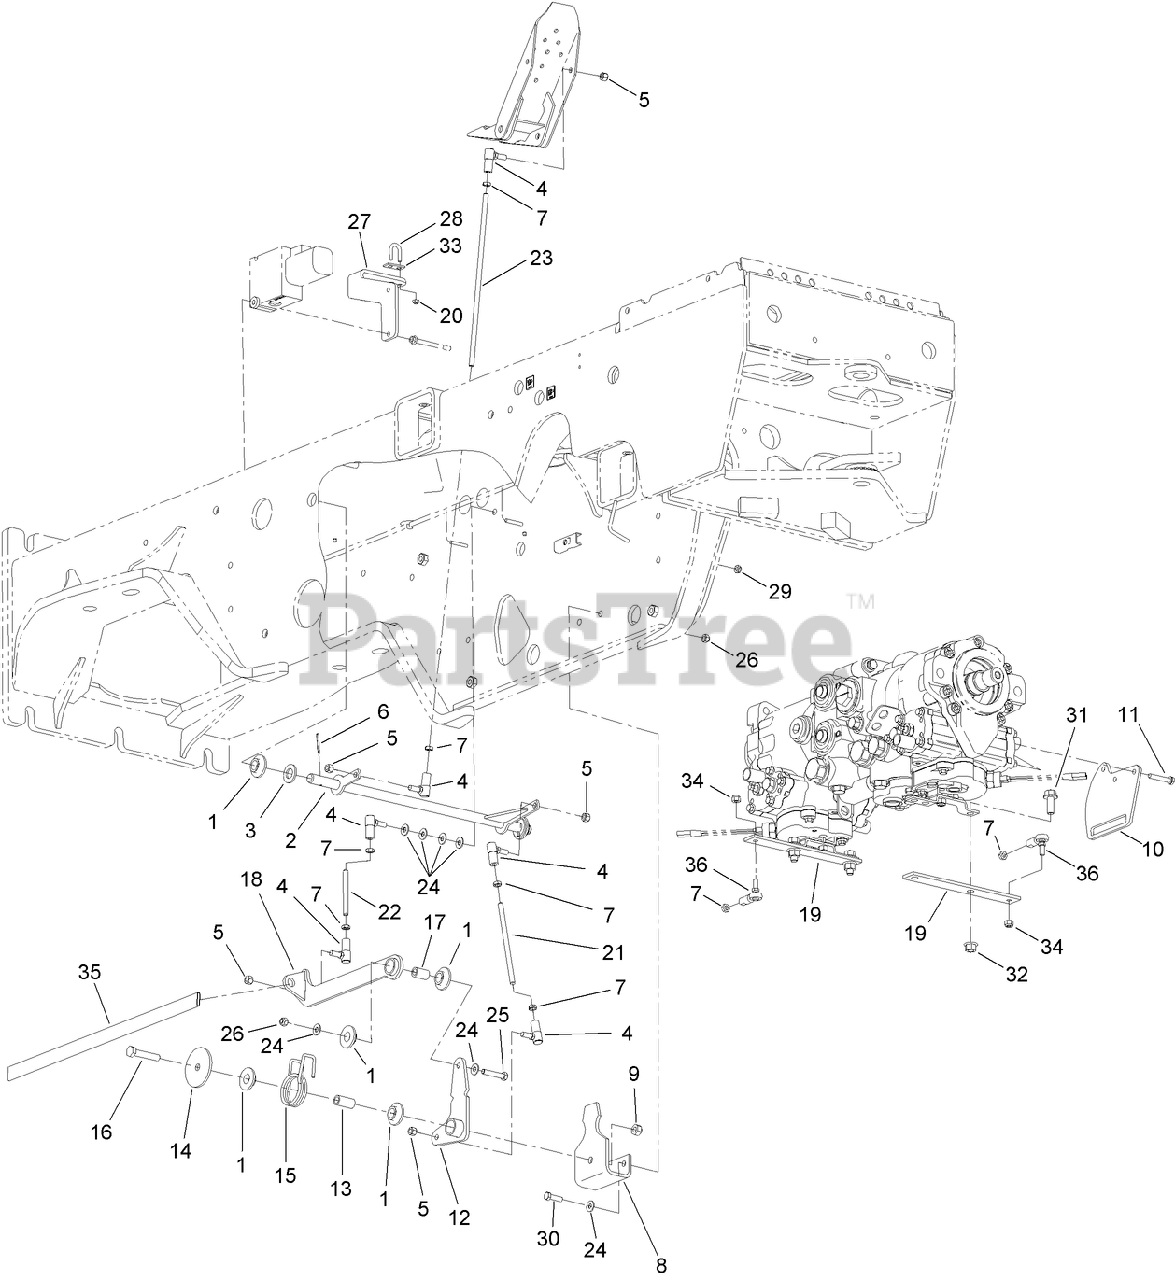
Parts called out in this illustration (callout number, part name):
1	BUSHING-INSERT, PLASTIC
2	SHAFT-CONTROL
3	WASHER-FLAT
4	JOINT-BALL
5	NUT-HEX
6	PIN-COTTER
7	NUT-HJ
8	CHANNEL-MOUNTING, BELLCRANK
9	LOCKNUT
10	STOP-LEVER, PUMP
11	SCREW-HH
12	PIVOT-BELLCRANK
14	WASHER-Special
16	SCREW-HH
17	SPACER-PIVOT, BELLCRANK
18	LINK-MOUNTING, CABLE
19	LEVER-CONTROL, PUMP
20	NUT-LOCK, CONE
21	ROD-Linkage
22	ROD-Linkage
23	ROD-Control
24	WASHER-FLAT
25	SCREW-HH
26	NUT-HEX
27	PLATE-MOUNT
29	NUT-HEX
30	SCREW-HH
31	SCREW-HHF
32	NUT-HF
34	NUT-LOCK
35	SLEEVE-PROTECTIVE
36	ROD END-FEMALE
